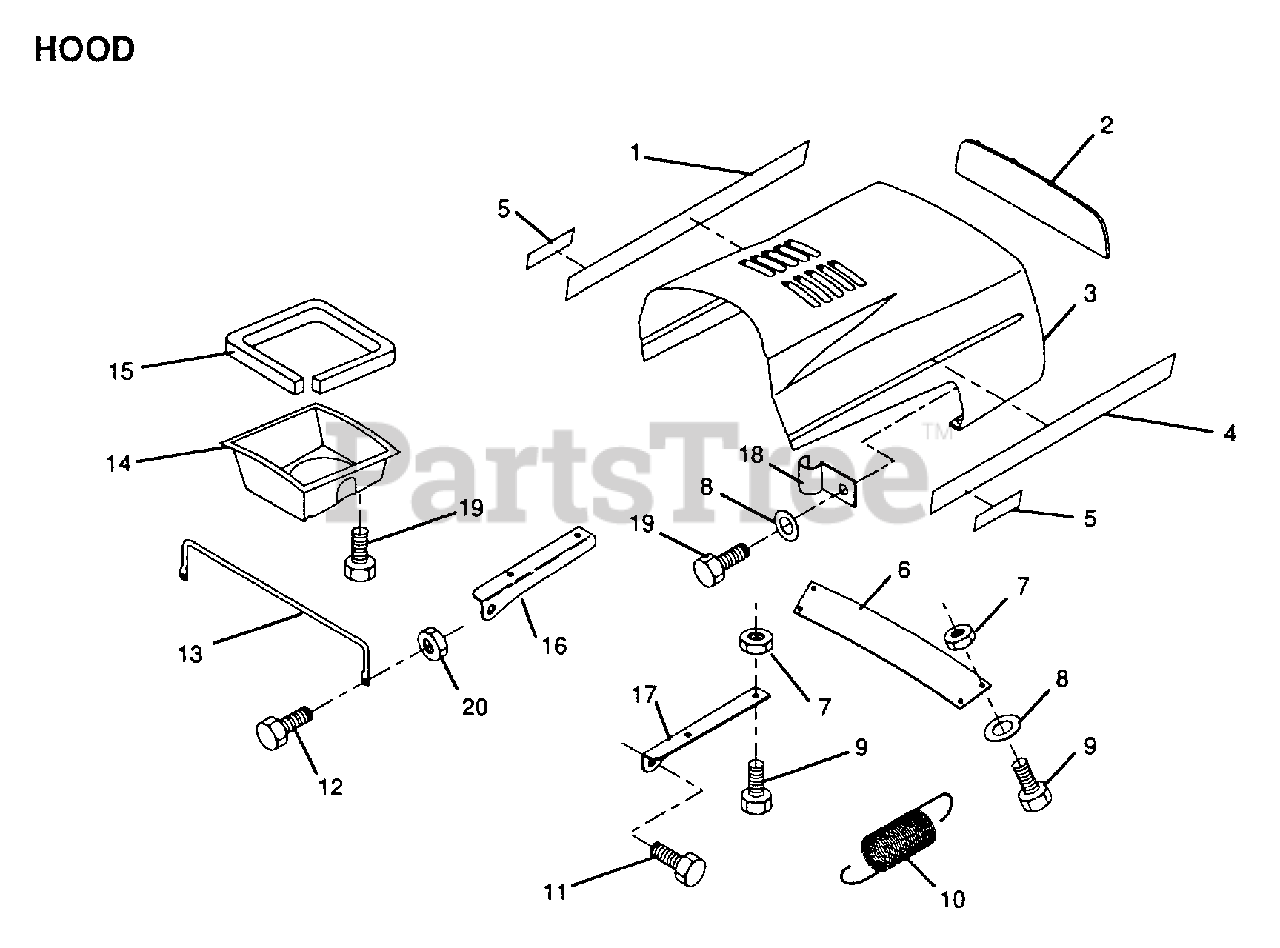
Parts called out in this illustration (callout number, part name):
2	LENS
3	HOOD&GRILL ASS'Y
6	"STRAP,GRILL"
7	PAL NUT
8	WASHER
9	BOLT
10	EXT SPRING
11	BOLT SHOULDER
13	"BRACE,HOOD"
14	"DUCT,AIR"
15	FOAM STRIP LT
16	BRKT HOOD LH
17	BRKT HOOD RH
18	CLIP T
